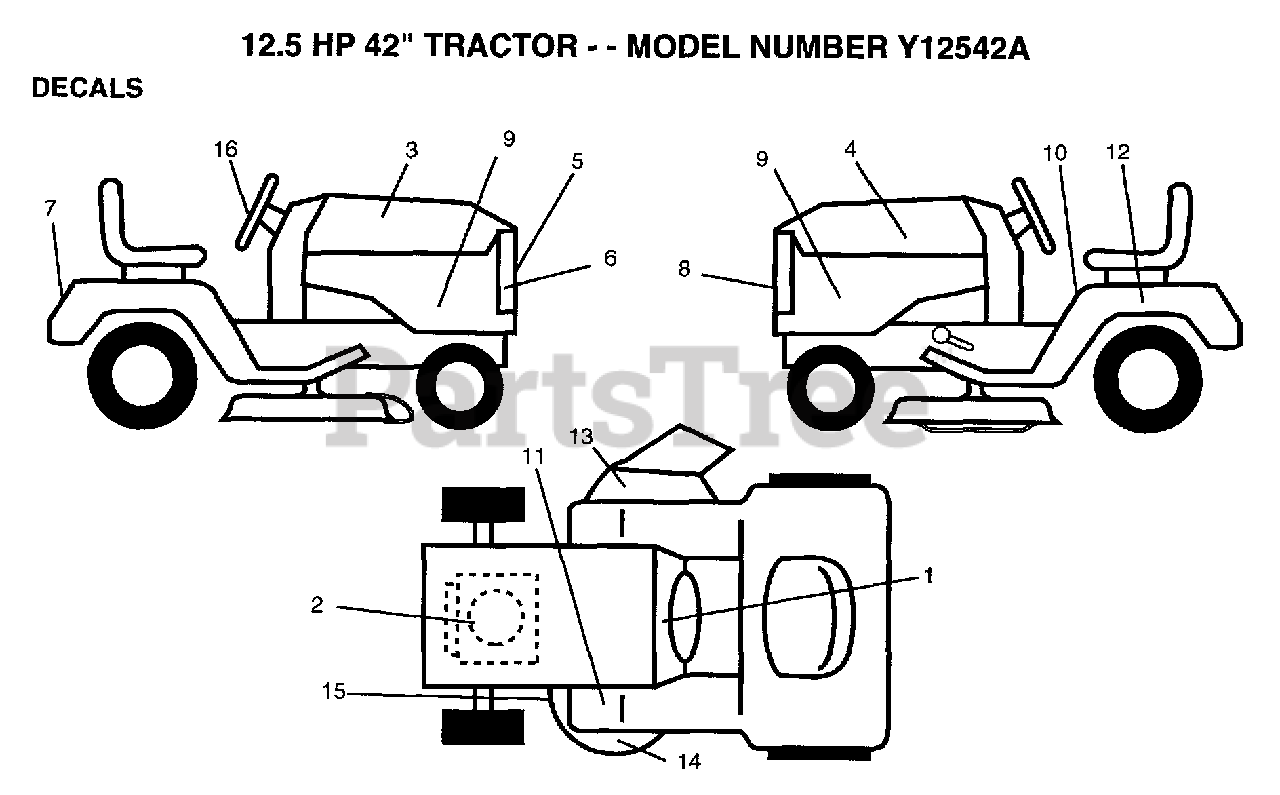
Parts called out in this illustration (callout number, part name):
5	DECAL.GRILL.YARDP
8	DECAL.GRILL.
9	DECAL.PANEL.SIDE
10	DECAL CAUTION
11	DECAL T
12	DECAL
13	"DECAL, WARNING"
15	DECAL
16	LEVER LIFT LR
